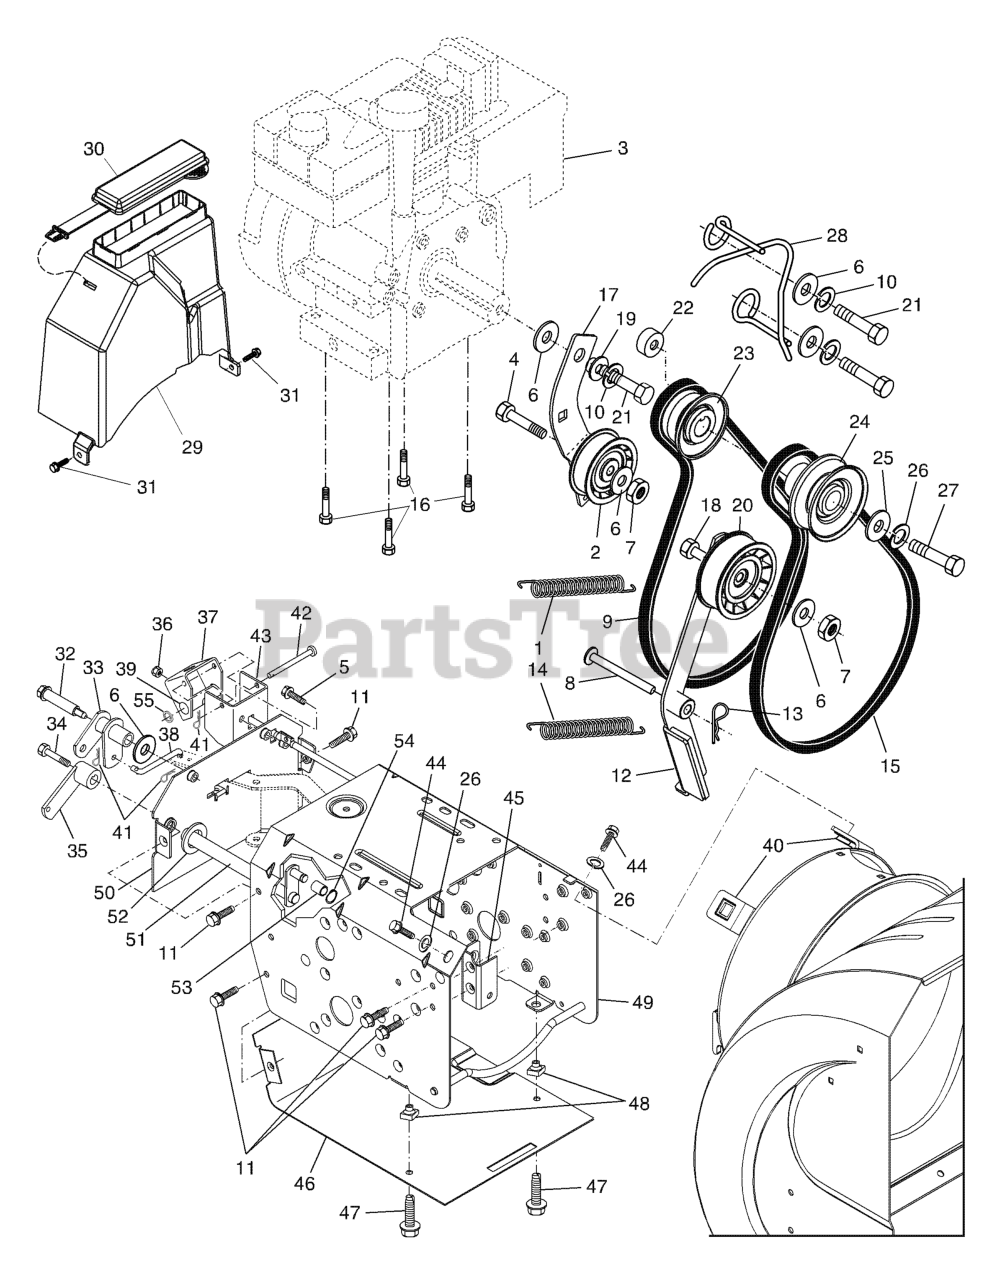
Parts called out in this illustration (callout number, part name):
1	RP SPRING, TRACTION IDLER
2	PULLEY.W/SPACER.2.25
4	BOLT.5/16-18X1-1/4 FULL.THREAD
5	SELF-TAPPING SCREW 5/16-18X3/4
6	STEEL WASHER
7	NUT.CENTERLOCK.5/16-
8	PIN, IDLER PIVOT
9	V-BELT, TRACTION DRIVE
10	WASHER.LOCK.HVY.HLCL.SPR.5/16
11	Screw, Hex Head 5/16-18 x 1/2
12	ARM ASSEMBLY, IMPELLER IDLER
13	RETAINER CLIP PM
14	SPRING, BRAKE
15	V-BELT, IMPELLER DRIVE
16	BOLT, ENGINE, 3/8-16
17	IDLER ARM
18	HEX BOLT
19	RP BUSHING, IDLER PIVOT
20	PULLEY.W/SPACER.2.75
22	SPACER, ENGINE PULLEY
23	PULLEY,ENGINE TRACTION DRIVE
24	PULLEY, ENGINE IMPELLER DRIVE
26	LOCKWASHER
27	SCREW, HEX HD 3/8-24 X 1-3/8
28	GUIDE, BELT
29	BELT COVER
30	COVER.STORAGE.SNOW
31	SCREW
32	BOLT, SHOULDER 5/16-18
33	BELLCRANK SHIFTER
35	ARM, AUGER CONTROL
36	NUT.71038.31-18.HEX.NYLOCK
37	BRACKET, PIVOT
38	LINK, SPEED CONTROL
39	TRUNNION, TRACTION
40	NUT, CAGE 3/8-16
41	RETAINER CLIP
42	PIN, PIVOT BRACKET
44	BOLT
45	BRACKET, IDLER PIVOT
46	PAN, FRAME BOTTOM
47	Screw, Hex Head 5/16-18 x 3/4
48	NUT.SPEED.5/16-18
49	FRAME ASSY
50	PLATE, FRAME END
51	CONTROL SHAFT WELDMENT
52	THRUST WASHER
53	ROLLER, ACTUATOR
54	RING.CRESENT
55	RETAINING RING LT
